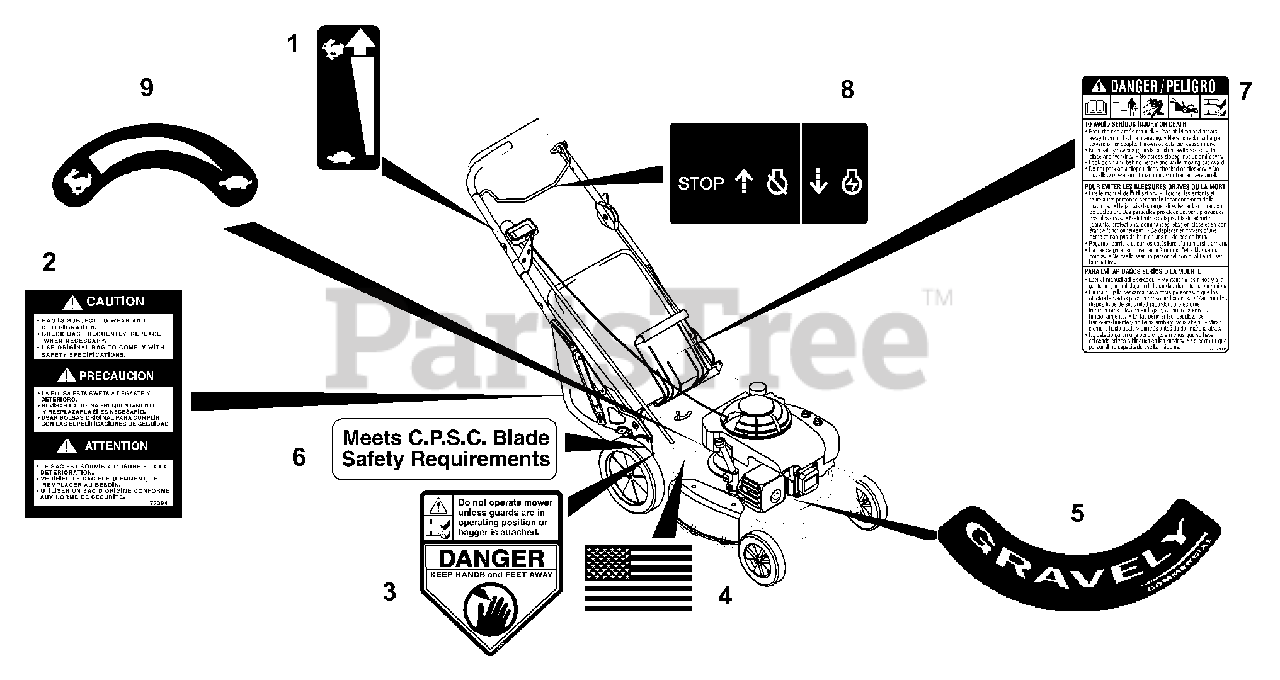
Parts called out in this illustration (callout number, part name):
1	DECAL-SPEED CONTROL
2	LABEL - BAGGER 21"
3	DECAL, CPSC DANGER
4	DECAL, AMERICAN FLAG
5	DECAL-COMMERCIAL
6	DECAL, C.P.S.C. BLADE SAFETY
7	DECAL, BILINGUAL DANGER
8	DECAL - ENGINE CONTROL
9	DECAL, TURTLE & RABBIT
